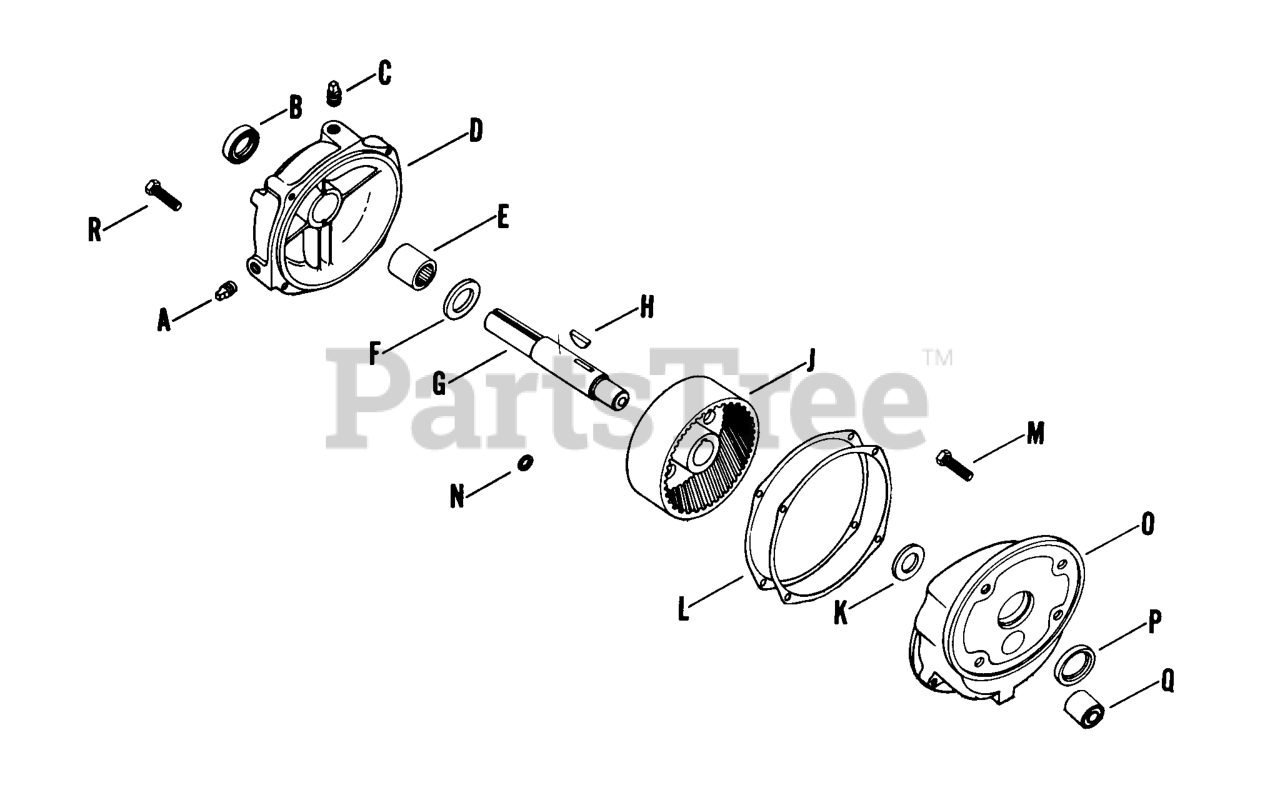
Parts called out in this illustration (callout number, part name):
A	PLUG,PIPE 1/4 NPTF SQUARE HD USE 25 139 53-S
B	SEAL - DISCONTINUED
C	PLUG - USE 41 139 01
D	COVER - DISCONTINUED
E	BEARING - DISCONTINUED
G	SHAFT - DISCONTINUED
H	KEY, 3/16" X 1"
J	GEAR - (#DSC)
M	SCREW - DISCONTINUED
O	HOUSING - (#DSC)
P	SEAL - USE 47 032 06
Q	BEARING
R	SCREW,CAP HD 5/16-18x2"
